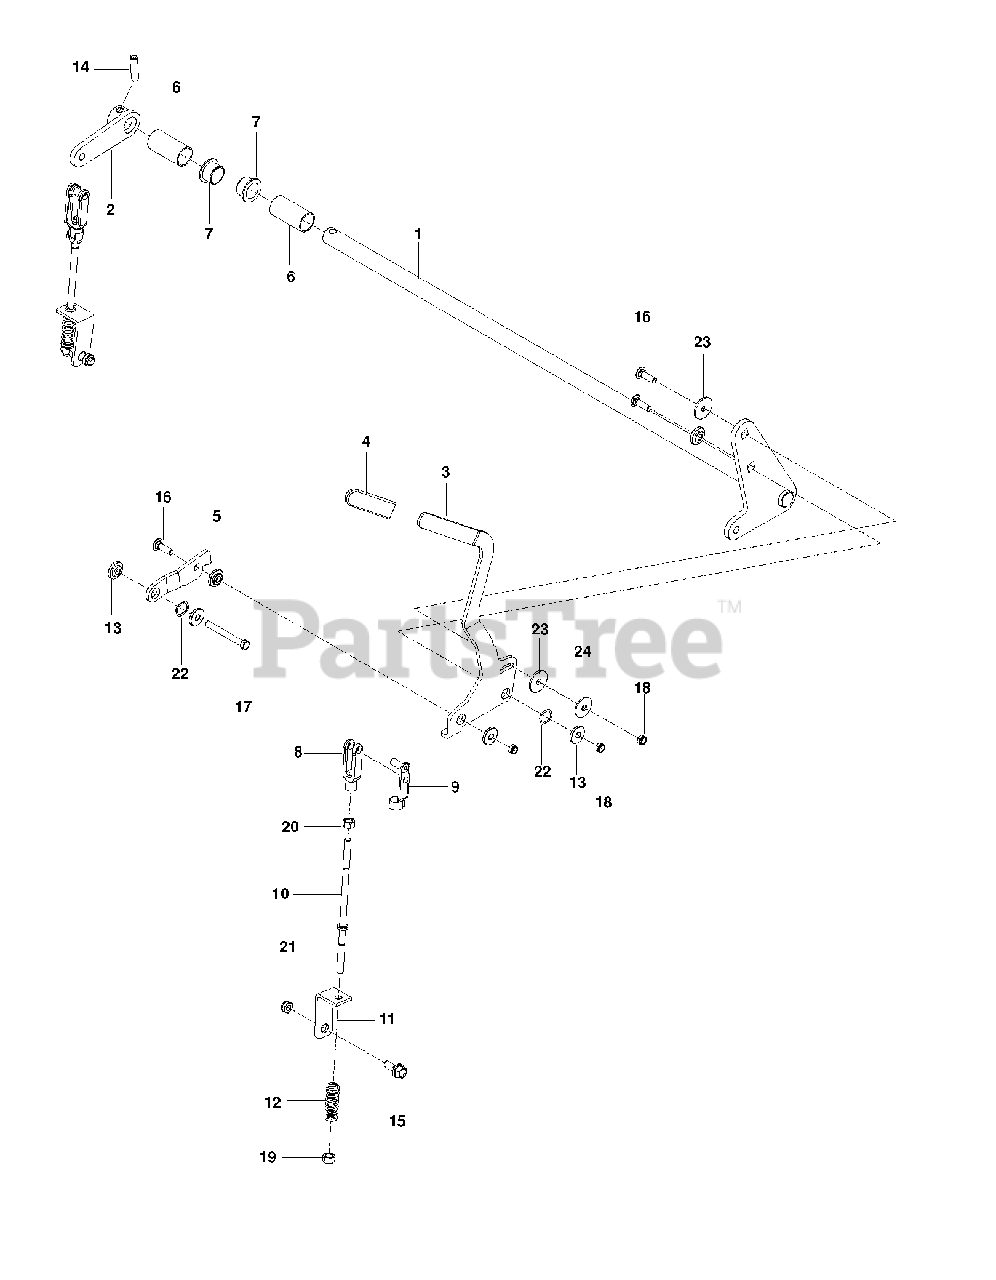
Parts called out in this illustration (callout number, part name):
1	SHAFT, BRAKE, WELDED
2	ARM, BRAKE, RT
3	LEVER.BRAKE.BLACK
5	LINK, FOLLOWER
6	SPACER, SHAFT, BRAKE
7	BEARING, FLANGE
8	YOKE 5/16 ADJ CLEVIS
9	PIN, CLEVIS SPRING, 3/8
10	LINKAGE, BRAKE
11	BRKT, BRAKE, BLK
12	SPRING, ENGAGEMENT
13	BUSHING, BRAKE
14	5/16 DIA ROLL PIN
15	BOLT, SHOULDER
16	RHSNB 3/8-16 X 1-1/4
17	HCS 3/8-16 X 3-1/4 GR5 ZD
18	NUT HEX 3/8-16 NYLON, THIN
19	NUT 5/16F NYLOC
21	5/16-18 THIN PROF NY
22	WASHER, .825 X 1.087, WAVE
23	WASHER, FRICTION, 1/8
24	CONE WASHER
